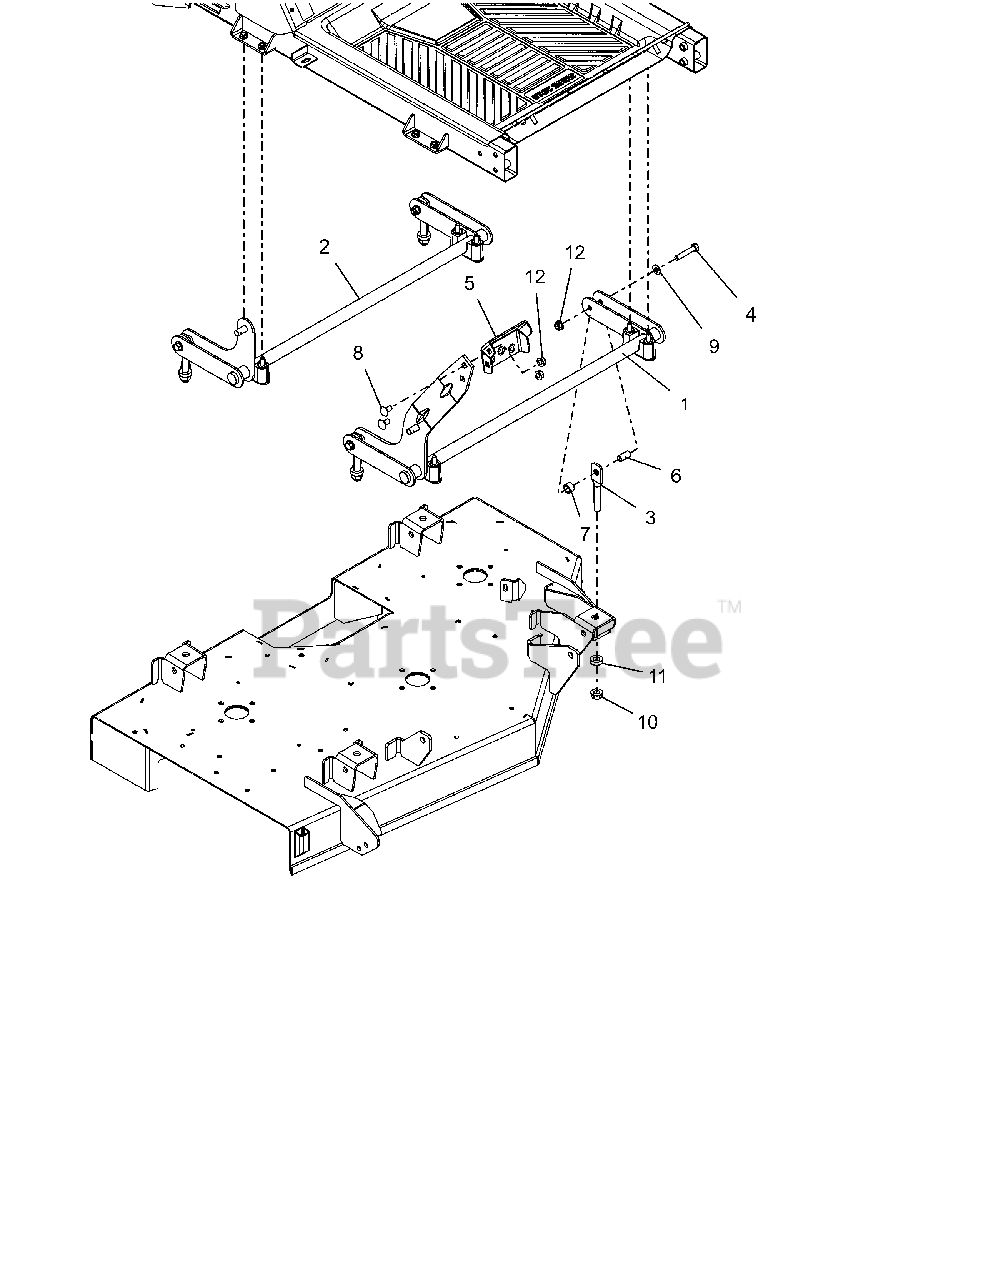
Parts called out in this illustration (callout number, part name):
1	WLDMT, FRONT DECK LIFT PIVOT
2	WLDMT, REAR DECK PIVOT
3	LINK, DECK (HOLE-SHORT)
4	BLT, HEX .38-16X2.00 G8 ZCC
5	PEDAL, DECK LIFT (BOLT ON)
6	BSHG-SLV .385X.500X1.045
7	BSHG-SLV .510X.751X.475
8	BLT,RHSN .38-16X.75 G5 BFP
9	WSHR,FLT .406X.812X.065 ZCC
10	NUT-LK-CTR-FLG .500-13 GG ZCC
11	WSHR, RUBBER
12	NUT-LK-CTR-FLG .375-16 GF ZCC
